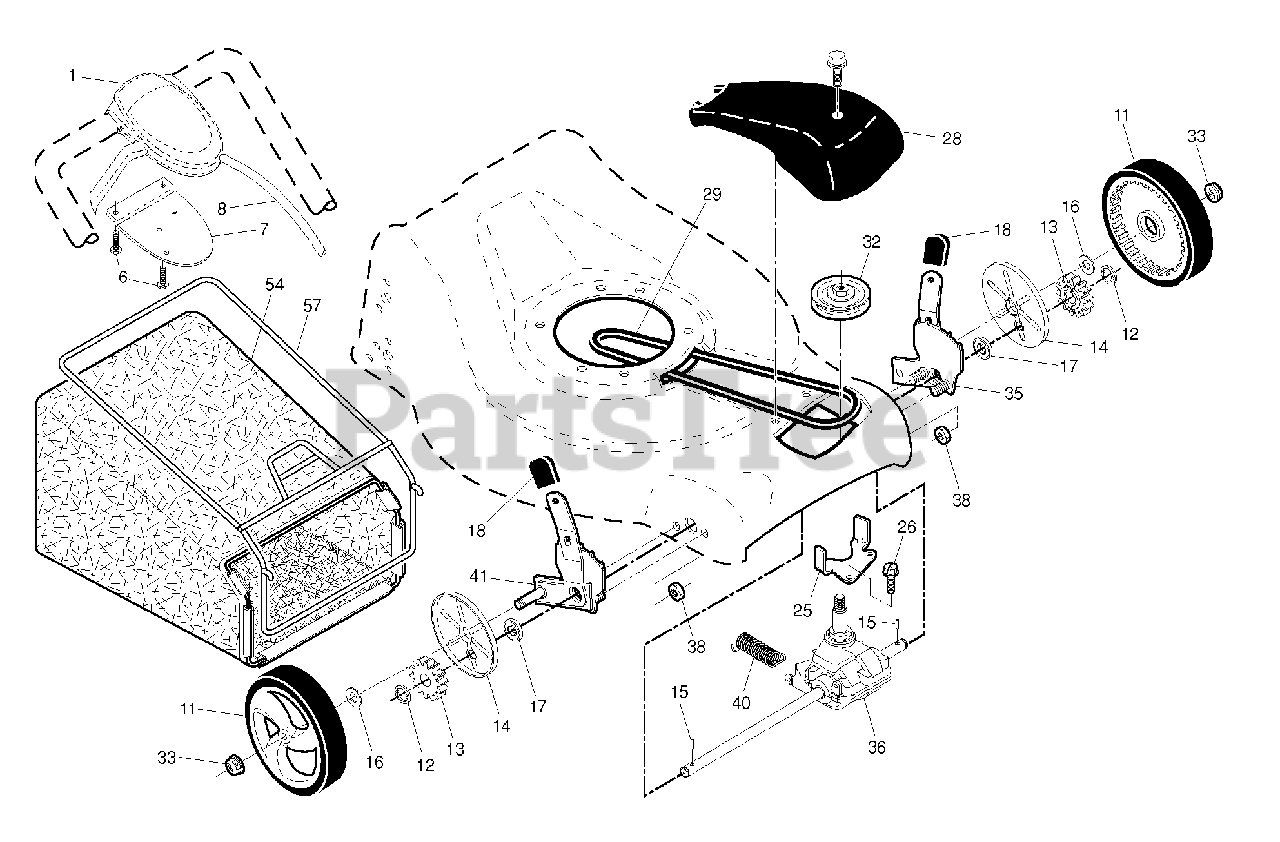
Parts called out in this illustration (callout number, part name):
6	SCREW, PHILLIPS HEAD 10 X 5/8
7	BRACKET.DRIVE.CONTROL.MOUNT
8	CABLE ASSEMBLY, DRIVE
12	E-RING 7/16 RE
13	PINION.14.TEETH.FGD
14	COVER.DUST.WHEEL
15	PAWL, DRIVE
16	WASHER FLUT
17	BEARING.ASM.
18	SELECTOR KNOB
25	BELT KEEPER
29	BELT.DRIVE.FG
32	RP PULLEY.DRIVE.EZ
33	NUT.HEX.FLANGE.3/8-16.LOCKNUT
35	KIT ADJUSTER ASM.438151.LT
36	TRANSMISSION.21.FGD.HT.VST
38	LOCKNUT
41	KIT ADJUSTER ASM.438148 .RT
57	FRAME.GBAG.21.FWGD
